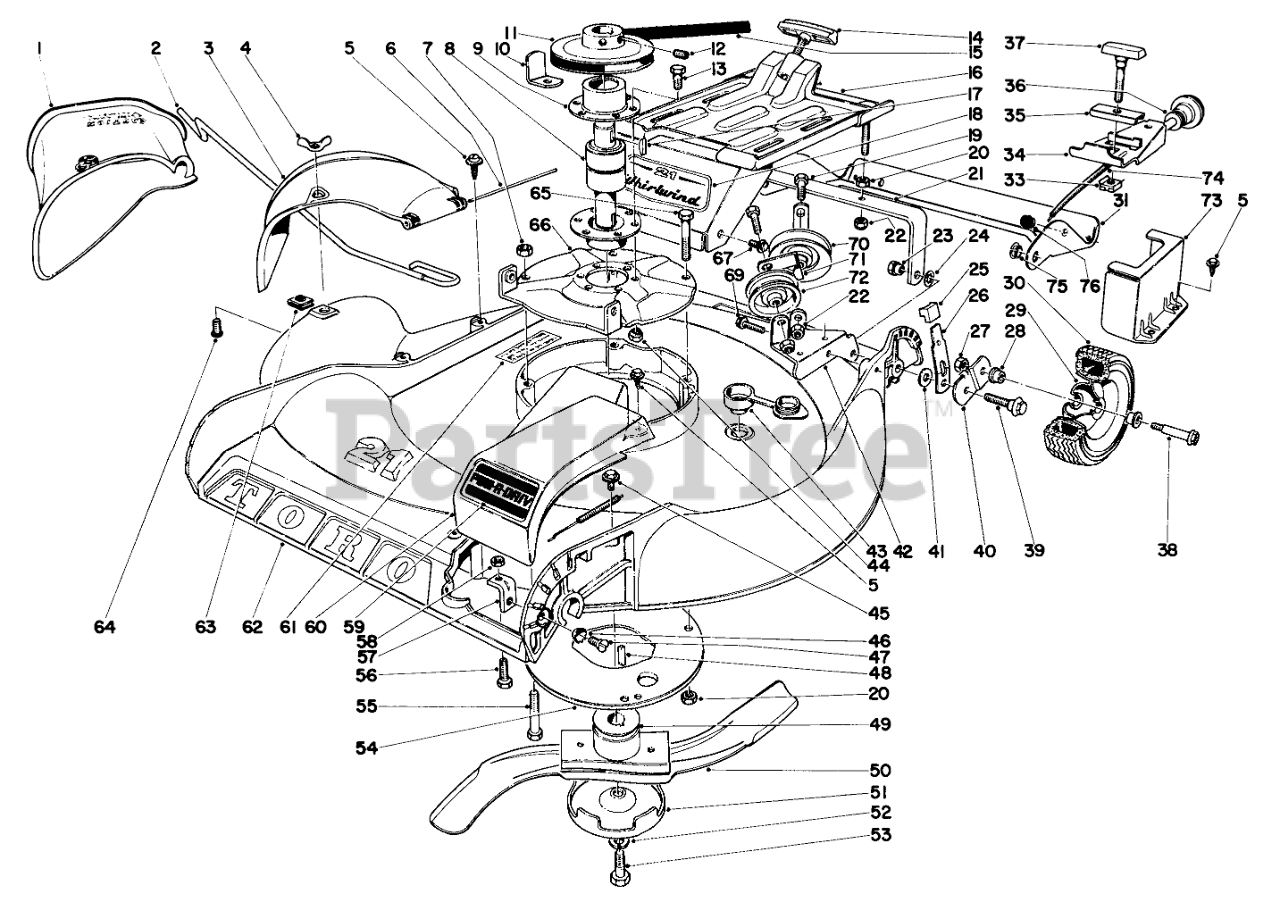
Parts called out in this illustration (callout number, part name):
1	BAG ATTACHMENT
2	Bag Hanger
3	Deflector
4	NUT-WING SPECL
5	Screw
6	HINGE PIN
7	NUT-HF
8	Spindle Bearing
9	BEARING HOUSING
10	Belt Retainer
11	Pulley
12	SCREW-SET, HSH
13	SCREW-HH
14	Clamp Assy.
15	V-Belt
16	Adapter Plate
17	KEY-WOODRUFF
18	Decal
19	SCREW-HH
20	NUT-HEX
21	Rear Support
23	Pivot Nut
24	WASHER-LOCK, INTERNAL
26	Spring Arm
27	Nut
28	FLANGE BUSHING
29	Wheel Assy. (Incl. Ref. #28)
30	8 TIRE
31	Safety Shield, Rear
33	Retaining Nut
34	Angle Bracket
35	Strap
36	WASHER-FLAT
37	Clamp Assembly
38	Wheel Bolt
39	Pivot Screw
40	Pivot Arm
41	WASHER-PIVOT
42	Idler Bracket
43	Washer Plug
44	NUT-LOCK, NI
45	Screw
46	Lockwasher
49	Retainer
50	Blade
51	ANTI-SCALP CUP
52	WASHER-LOCK
53	SPECIAL SCREW
54	Grass Guard
55	SCREW-HH
56	SCREW
57	ADJ BRACKET
58	NUT-JAM
59	Decal
60	Belt Guard
61	Decal
62	Housing
63	NUT-SPEED
65	3/8-16 X 2-3/4 CAPSCR
66	Mounting Plate
67	Sems Screw
69	Sems Screw
70	IDLER PULLEY R
71	Belt Retainer
72	PULLEY-IDLER
73	Belt Guard
74	Control Assy
75	Nyliner
76	SKID BUTTON
